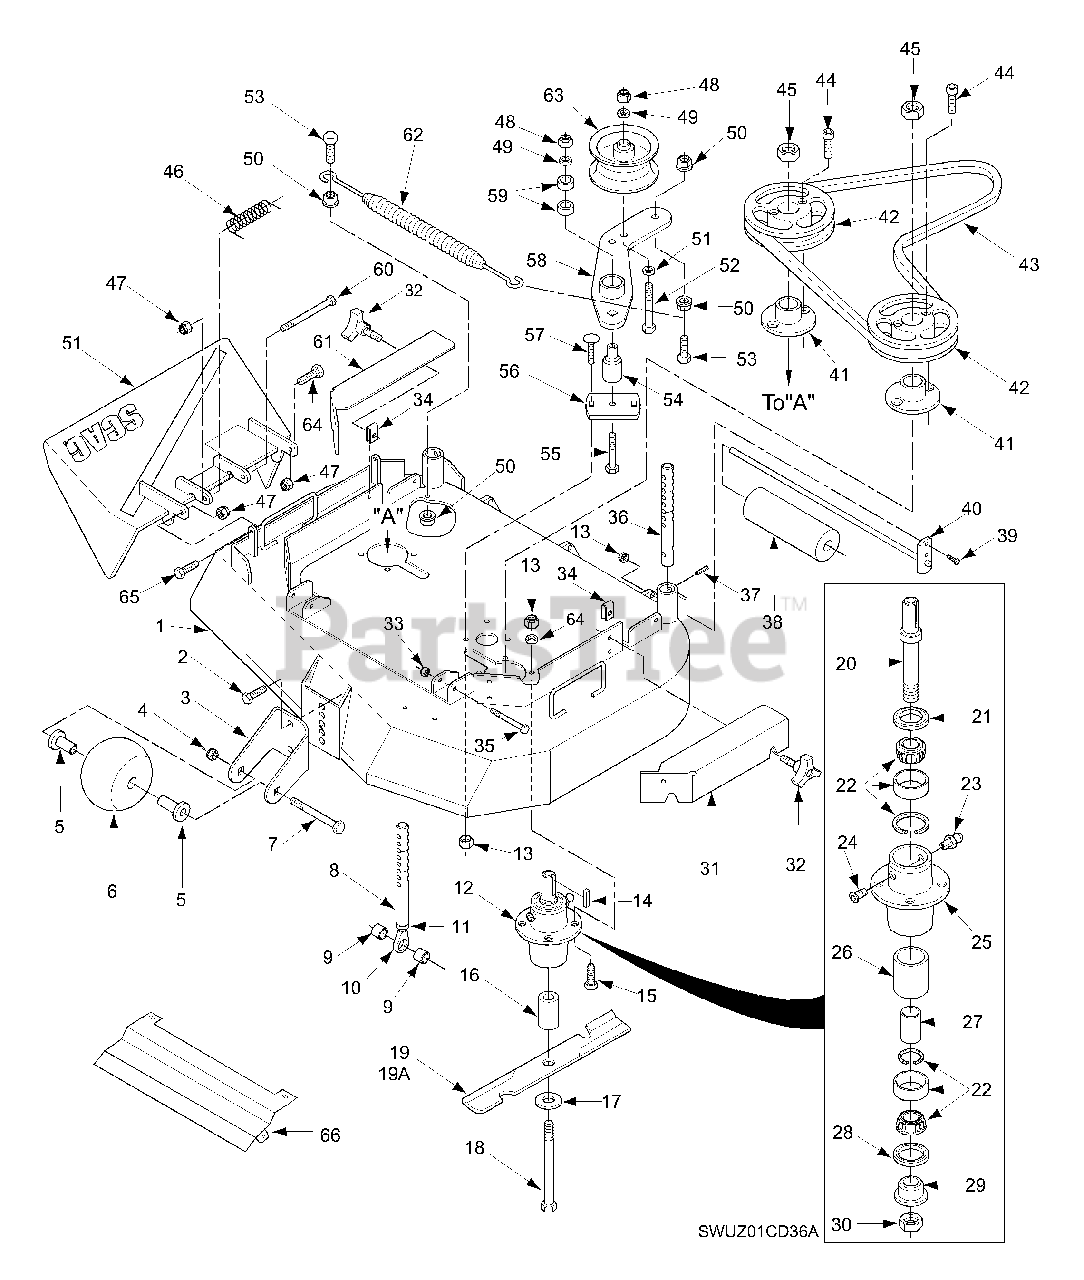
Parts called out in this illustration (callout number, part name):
1	Cutter Deck
2	Capscrew, 3/8-16 x 1.0" Serrated Flange Hex Hd
3	Bracket, Anti-Scalp Wheel
4	Lock Nut, 3/8-16 Center Lock
5	Bushing, 376 ID Oilite
6	Wheel, Anti-Scalp
7	Bolt, Carriage 3/8-16 x 4.0"
8	Pin Assy., Deck Adj.
9	Spacer, Deck Adjustment Pin
10	Rod End, Male 3/8-24 RH Thread
11	Nut, 3/8-24 Jam
12	Spindle Assembly
13	Nut, 5/16-18 Serrated Flange
14	Key,1/4 x 1/4 x 2.0"
15	Bolt, Hex Head 5/16-18 x 1.25"
16	Spacer, Spindle
17	Flatwasher, 5/8 W
18	Bolt, Hex Head 5/8-11 x 9.50"
19	Cutter Blade, 18"
19A	Cutter Blade, 18" Hi Lift
20	Spindle Shaft
21	Seal, Cutter Spindle Top
22	Tapered Bearing Set (Two Bearings W/Race)
23	Grease Fitting
24	Relief Fitting, Cutter Spindle
25	Spindle Housing
26	Spacer, Outside
27	Spacer, Inside
28	Seal, Cutter Spindle Bottom
29	Spindle Bushing
30	Nut, Spindle
31	Belt Cover, LH
32	Wing Nut, 3/8-16
33	Nut, 3/8-16 Elastic Stop
34	U-Nut, 3/8-16
35	Bolt, Hex Head 3/8-16 x 2.50"
36	Pin, Deck Adj. Rear
37	Pin, Sloted Spring 3/16 x 1.50"
38	Guide, Roller
39	Bolt, Hex Head 5/16-18 x 1.0"
40	Roller Shaft
41	Tapered Hub
42	Pulley
43	Belt, Cutter Deck
44	Capscrew, Socket Head. 1/4-20 x 1.375"
45	Hex Nut, 5/8-11
46	Spring, Chute Return
47	Hex Nut, 5/16-18 Elastic Stop
48	Hex Nut, 3/8-16 Elastic Stop
49	Flatwasher, 3/8 (.938 x .391 x .105)
50	Nut, 3/8-16 Serrated Flange
51	Discharge Chute
52	Capscrew, Hex Head 3/8-16 x 3.75"
53	Capscrew, Hex Head 3/8-16 x 1.50"
54	Pivot, Idler - Long
55	Capscrew, Hex Head 38/16 x 3.25"
56	Base, Idler Pivot
57	Bolt, Carriage 5/16-18 x 1.0"
58	Idler Arm Weldment
59	Ball Bearing
60	Bolt, Hex Head 5/16-18 x 4.25"
61	Belt Cover, RH
62	Spring, Deck Idler
63	Pulley, Idler
64	Bolt, Hex Head 5/16-18 x 1.5"
65	Bolt, Hex Head 5/16-18 x 1.75"
66	Heatshield
